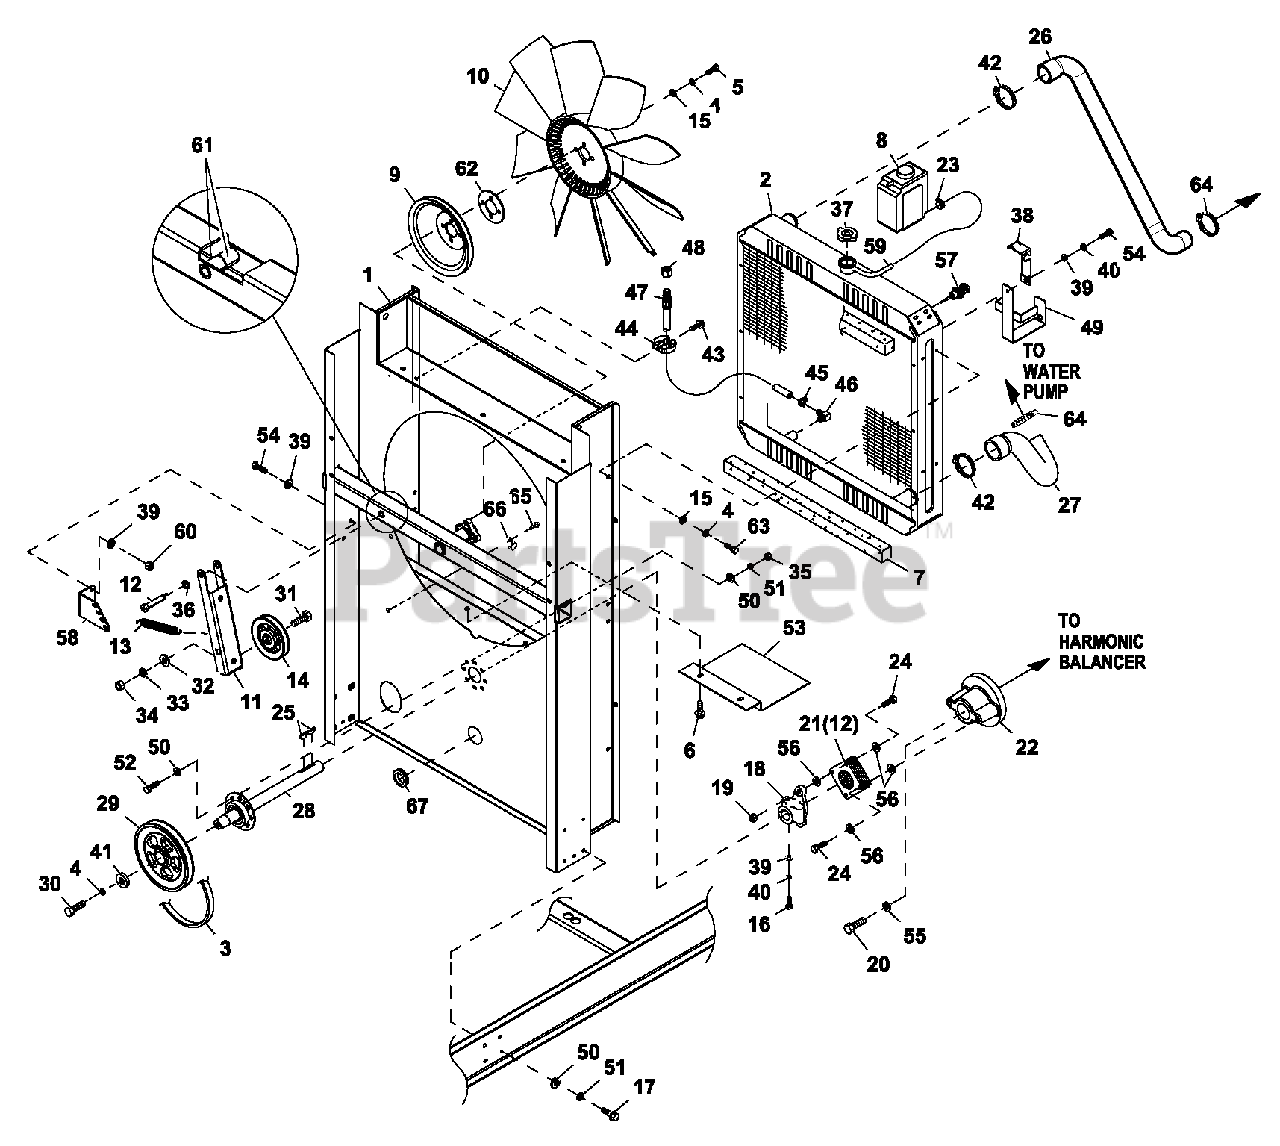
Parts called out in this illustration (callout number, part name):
1	WELDMENT RADIATOR SUPPORT C5
2	RADIATOR 680X680X70 CPL
3	V-BELT 31/64" X 62-3/8"
4	WASHER LOCK M10
5	SCREW HHC M10-1.5X30C10.9
6	SCREW THF M6-1 X 16 N WAZ/JS
7	TAPE FOAM 1 X 1 (26.75" LG)
8	TANK COOLANT RECOVERY
9	PULLEY FAN V-GROOVE 9"
10	FAN 26" LH ROTATION
11	ARM BELT TENSIONER
12	SHOULDER BOLT 1/2 X 2-1/4"
13	SPRING TENSION CPL
14	PULLEY V-BELT 4" FLANGED
15	WASHER FLAT 3/8-M10 ZINC
16	SCREW HHC M8-1.25X 45 C 8.8
17	SCREW HHFC M6-1.0 X 20 G8.8
18	HUB FLEX PLATE
19	NUT HEX LOCK 5/16-24 NY INS
20	SCREW HHC M12-1.5X 6 0 G8.8
21	DISK FLEX
22	COUPLING FLEX HUB MACHINED
23	CLAMP HOSE BAND 1/4
24	SCREW HHC 5/16-24X1.124
25	KEY WOODRUFF 4 X19D
26	HOSE RADIATOR UPPER C5 CPL
27	HOSE RADIATOR LOWER C5 CPL
28	ASSY BRG/SHAFT CPL FANDRIVE
29	PULLEY 5.5" DIA MACHINED
30	SCREW HHC M10-1.5X30 G8.8
31	SCREW HHC 1/2-13X2" G8
32	WASHER FLAT 1/2 ZINC
33	WASHER LOCK 1/2
34	NUT HEX 1/2-13 STEEL
35	NUT HEX M6 X 1.0 G8 YEL CHR
36	WASHER NYLON .50 X .87 X .06
37	CAP RADIATOR 13 PSI
38	BRACKET, SIGNAL CONDITIONER
39	WASHER FLAT 5/16-M8 ZINC
40	WASHER LOCK M8-5/16
41	SPACER .5 X 1.5 X .25 STL/ZINC
42	CLAMP HOSE #28 1.32-2.25
43	SCREW HHTT M4-0.7 X 8 BP
44	SPRING CLIP HOLDER .37- 62
45	CLAMP HOSE .38- 87
46	BARBED EL 90 3/8 NPT X 3/8
47	HOSE DRAIN ASSY 28"
48	CAP HEX 1/4 NPT BRASS
49	BRACKET COOLANT TANK
50	WASHER FLAT 1/4-M6 ZINC
51	WASHER LOCK M6-1/4
52	SCREW HHC M6-1.0 X 20 G8.8
53	SHIELD RADIATOR
54	SCREW HHC M8-1.25X 20 G8.8
55	WASHER LOCK M12
56	WASHER FLEX (THIN)
57	PROBE COOLANT LEVEL 3/8-18NPTF
58	BRACKET TENSIONER SPRING
59	HOSE 9/32 ID (43"LG)
60	NUT HEX LOCK M8-1.25 NY INS
61	BEARING SLEEVE 1/2/X 3/4X1
62	SPACER CPL COOLING FAN 1/8"
63	SCREW HHC M10-1.5X 20 C 8.8
64	CLAMP HOSE #24 B1.06-2.00
65	SCREW HHTT M6-1.0X16ZYC
66	CLAMP STUVNL.62X.406Z
67	GROMMET 1.37 X .0 6 X 1.00
